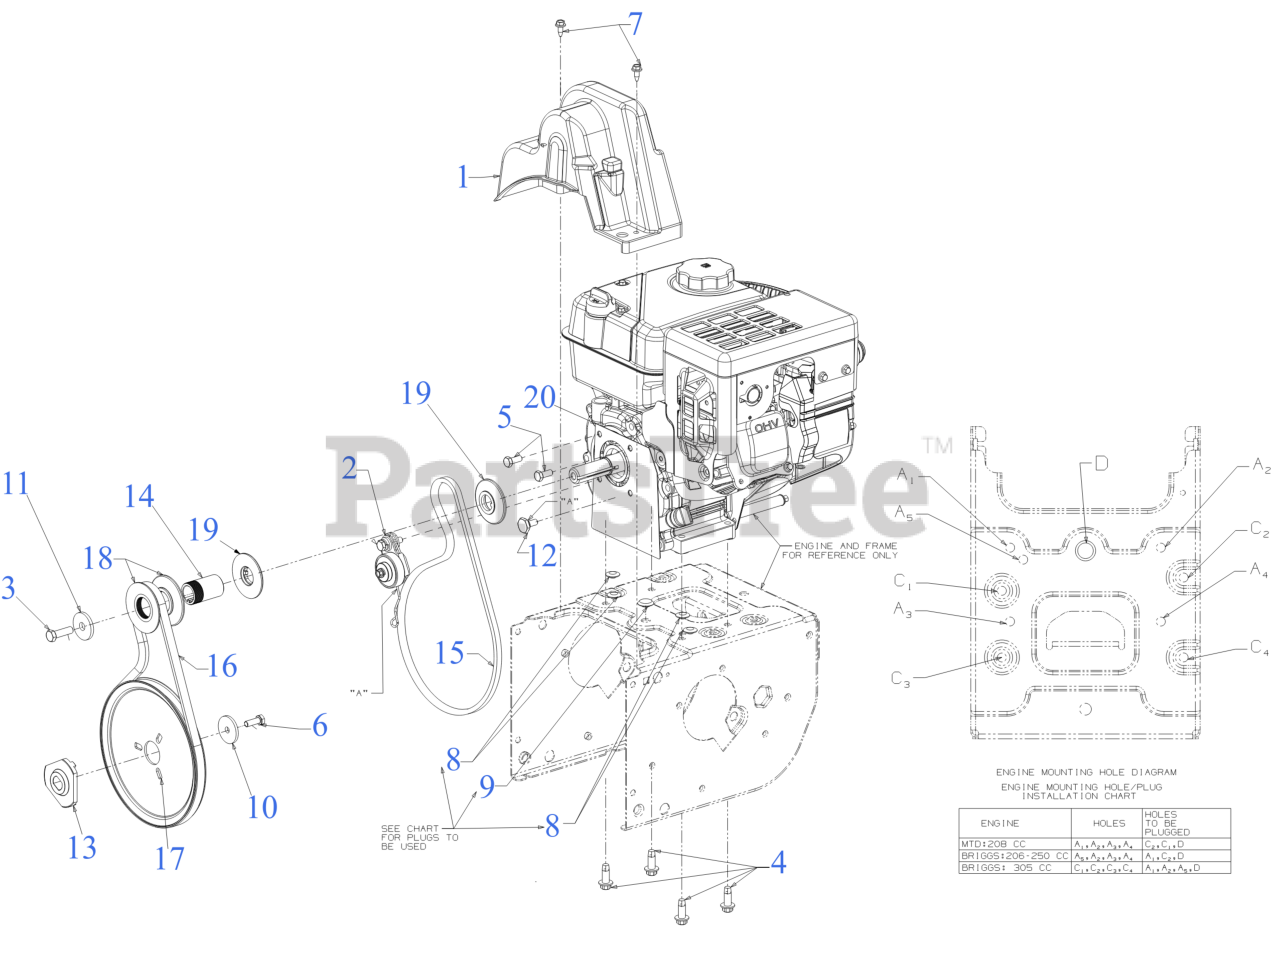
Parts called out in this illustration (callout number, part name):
1	BELT COVER SERVICE KIT (631-05322)
1	HEX SCREW #12-16 x .50
2	IDLER ASSEMBLY
3	SCREW 3/8-24X1.25
4	SCREW 3/8-16 x 1
5	SCREW 5/16-24 x .750 GR5
6	SCREW 5/16-24 x .875 GR5
7	SCREW 1/4-20X.625
8	PLUG-3/8 DIA ID x 3/32
9	PLUG-1/2 ID x 3/32
10	FLAT WASHER
11	FLAT WASHER .45 x 1.5 x .172 HT
12	SHOULDER SCREW
13	ADAPTER PULLEY .75 DIA W/DD
14	PULLEY SPACER
15	V-BELT 3/8 x 35
16	V-BELT .500 x 35.00LG
17	AUGER PULLEY
18	HALF PULLEY 4L V x 2.6 OD
19	HALF PULLEY 3/8-V x 2.2
20	COVER PLATE
